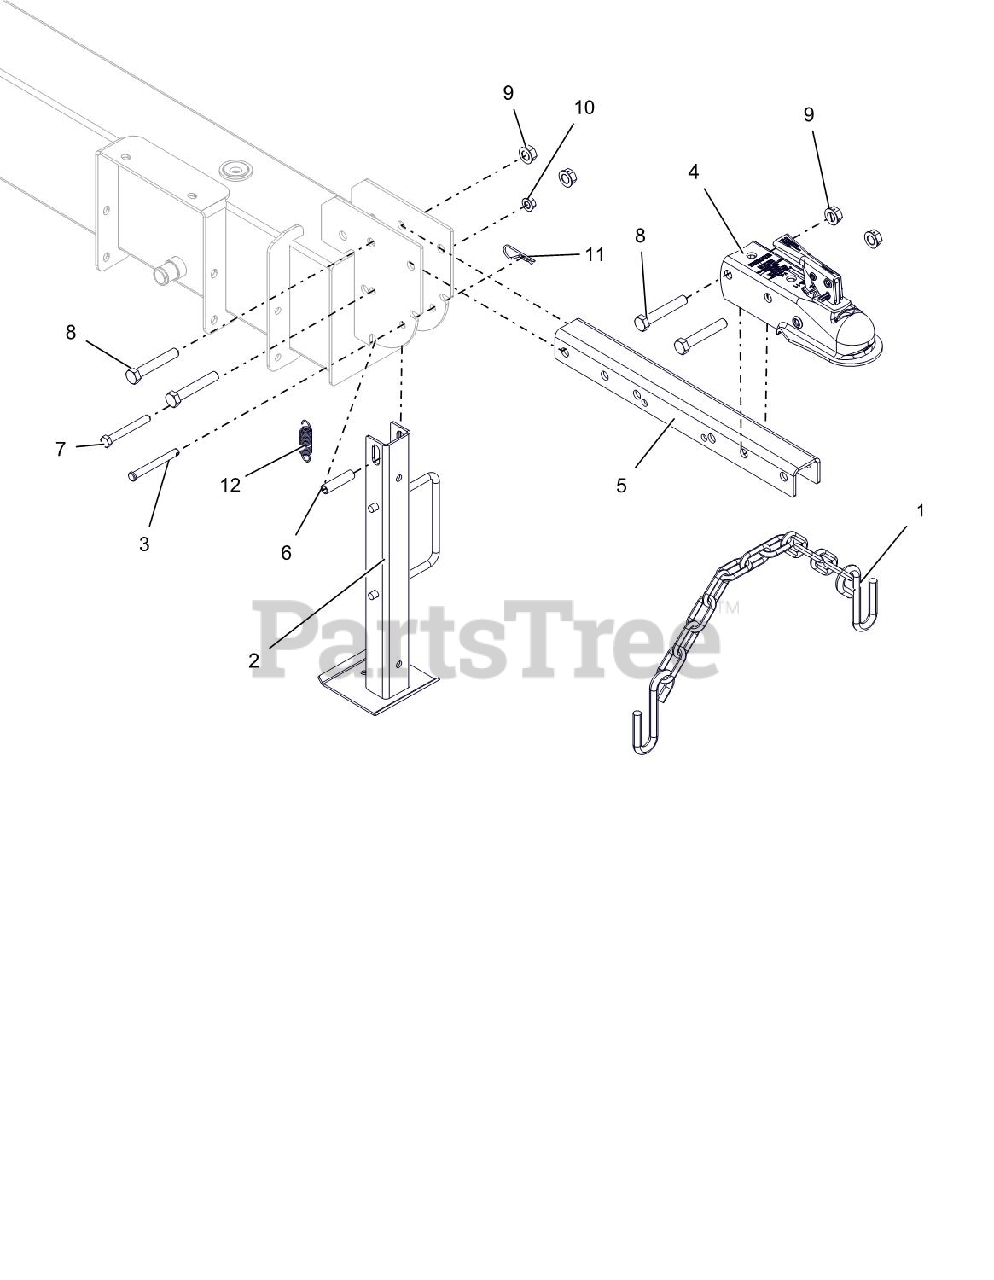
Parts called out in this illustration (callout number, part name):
1	CHAIN, SAFETY
2	WLDMT, JACK STAND
3	PIN-CLEV .371X3.25 YWZC
4	COUPLER-BALL 2.000"
5	HITCH BAR W/SAFETY DECAL-CE
6	SPCR, WHEEL .385X.500X2.00
7	@BLT-HEX .38-16X3.00 GR5 YWZC
8	@BLT-HEX .50-13X3.00 GR5 YWZC
9	NUT-LK-CTR-FLG .50-13 YWZC
10	@NUT-LK-TOP-FLG .38-16 YWZC
11	HAIRPIN, #7 CLIP .094X2.31 YWZ
12	SPRG, TENSION .063X.625X2.50
